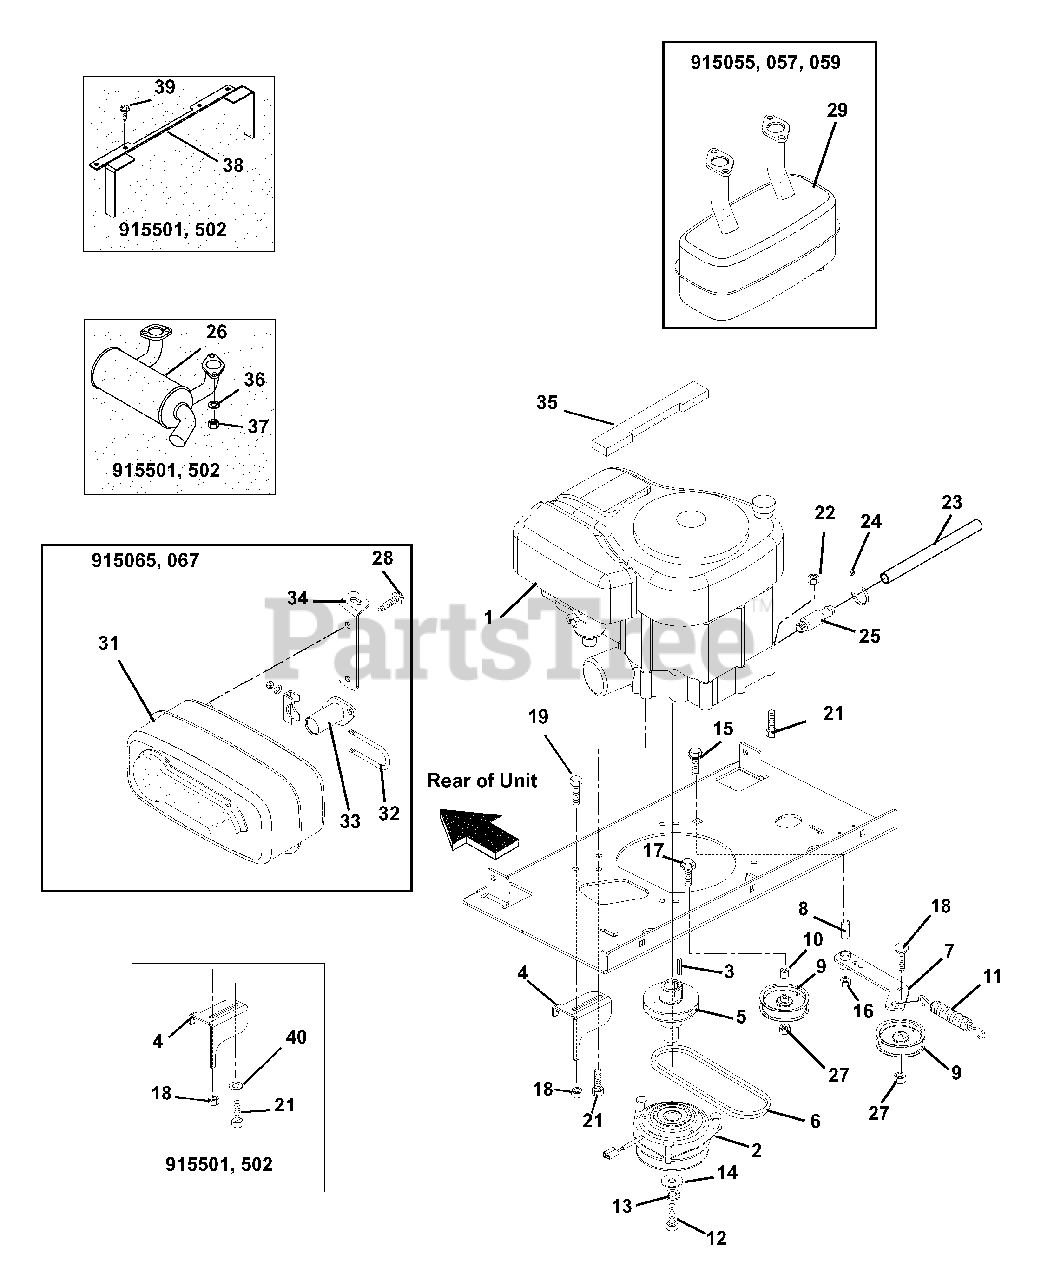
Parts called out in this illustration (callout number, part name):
1	ENGINE, KOHLER COURAGE
1	ENGINE, 19HP KOHLER
1	ENGINE, 23HP KOHLER
1	ENGINE, 15HP KAW FH451V
1	ENGINE, 17 HP KAWASAKI FH500V
2	CLUTCH,ELECTRIC PTO
2	ELECTRIC CLUTCH/BRAKE (3.4AMP)
3	KEY-SQ .25 X 1.50 X .25 SAE
4	STOP, CLUTCH
5	EXTENSION, CRANK SHAFT
6	V-BELT, HA-RAW EDGE
6	BELT,HA WRAPPED
7	WMT,IDLER
8	BSHG-SLV .500X.750X1.560
9	IDLER-FLAT 4.00 X .38 NWHAMSHR
10	BSHG,SPCR .41 X .75 X .88 PM
11	SPRING, EXT
12	BLT-HEX .44-20X4.50 GR8 YWZC
13	@WSHR-LK .44X.109 REG YWZC
14	WSHR-FL-STL .469X2.00X.25 YWZC
15	@BLT-HEX .50-13X2.50 GR5 YWZC
16	@NUT-LK-TOP-FLG .50-13 YWZC
17	@BLT-RDHDSQNK .38-16X2.00 G5YZ
18	@BLT-RDHDSQNK .38-16X1.25 G5YZ
19	@BLT-HEX .38-16X1.00 GR5 YWZC
20	HEAT SHIELD
21	@BLT-HEX .31-18X1.75 GR5 YWZC
21	@SCR-TAP .38-16X1.00 HWH TR YZ
22	@NUT-LK-NYL-FLG .31-18 YWZC
23	TUBE, OIL DRAIN
24	CABLE TIE LG 5-1/2
25	VALVE, OIL DRAIN
26	MUFFLER, KAW. (COMPACT-Z)
27	@NUT-LK-CTR-JAM .375-16 YWZC
28	@SCR-TAP .25-20X.50 HWH TR YWZ
29	MUFFLER
30	@NUT-LK-NYL-FLG .38-16 YWZC
31	MUFFLER, KOHLER COURAGE SINGLE
32	MUFFLER CLAMP
33	WMT, MANIFOLD
34	MUFFLER BRACKET
35	FOAM SEAL, 1.5"X3.5"X24"
36	@WSHR-LK .31X.078 REG YWZC
37	NUT-HEX M8-1.25 YWZC
38	HEAT SHIELD
39	@SCR-TAP .31-18X.50 HWH TR YWZ
40	WSHR-FL-STL .328X1.0X.094 YWZC
